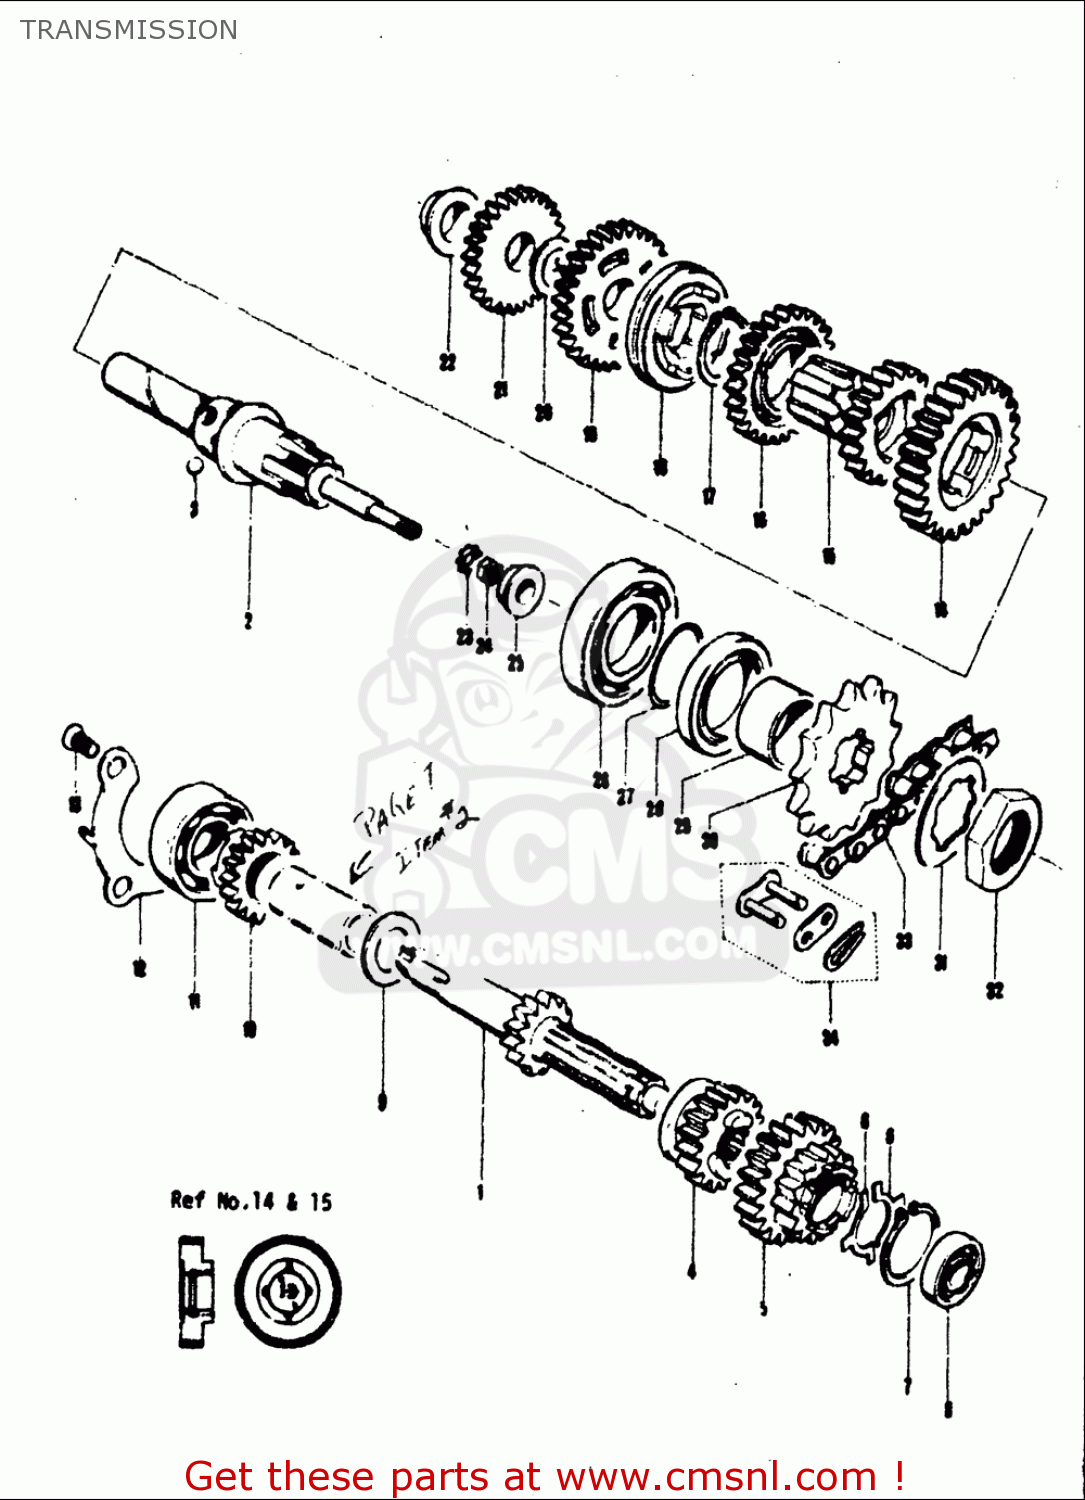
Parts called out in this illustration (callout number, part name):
3	BALL
7	RING,SNAP
8	BEARING(12X28X8)
9	SHIM(17X30X1)
11	BEARING(30X62X10)
17	RING,SNAP
20	SHIM, 15X24X1.0
23	LOCK WASHER
24	NUT
25	OIL SEAL
26	BEARING(25X52X15)
27	O RING(D:1,ID:24.5)
28	SEAL,OIL(30X44X6)
30	SPROCKET,ENGINE
32	NUT
